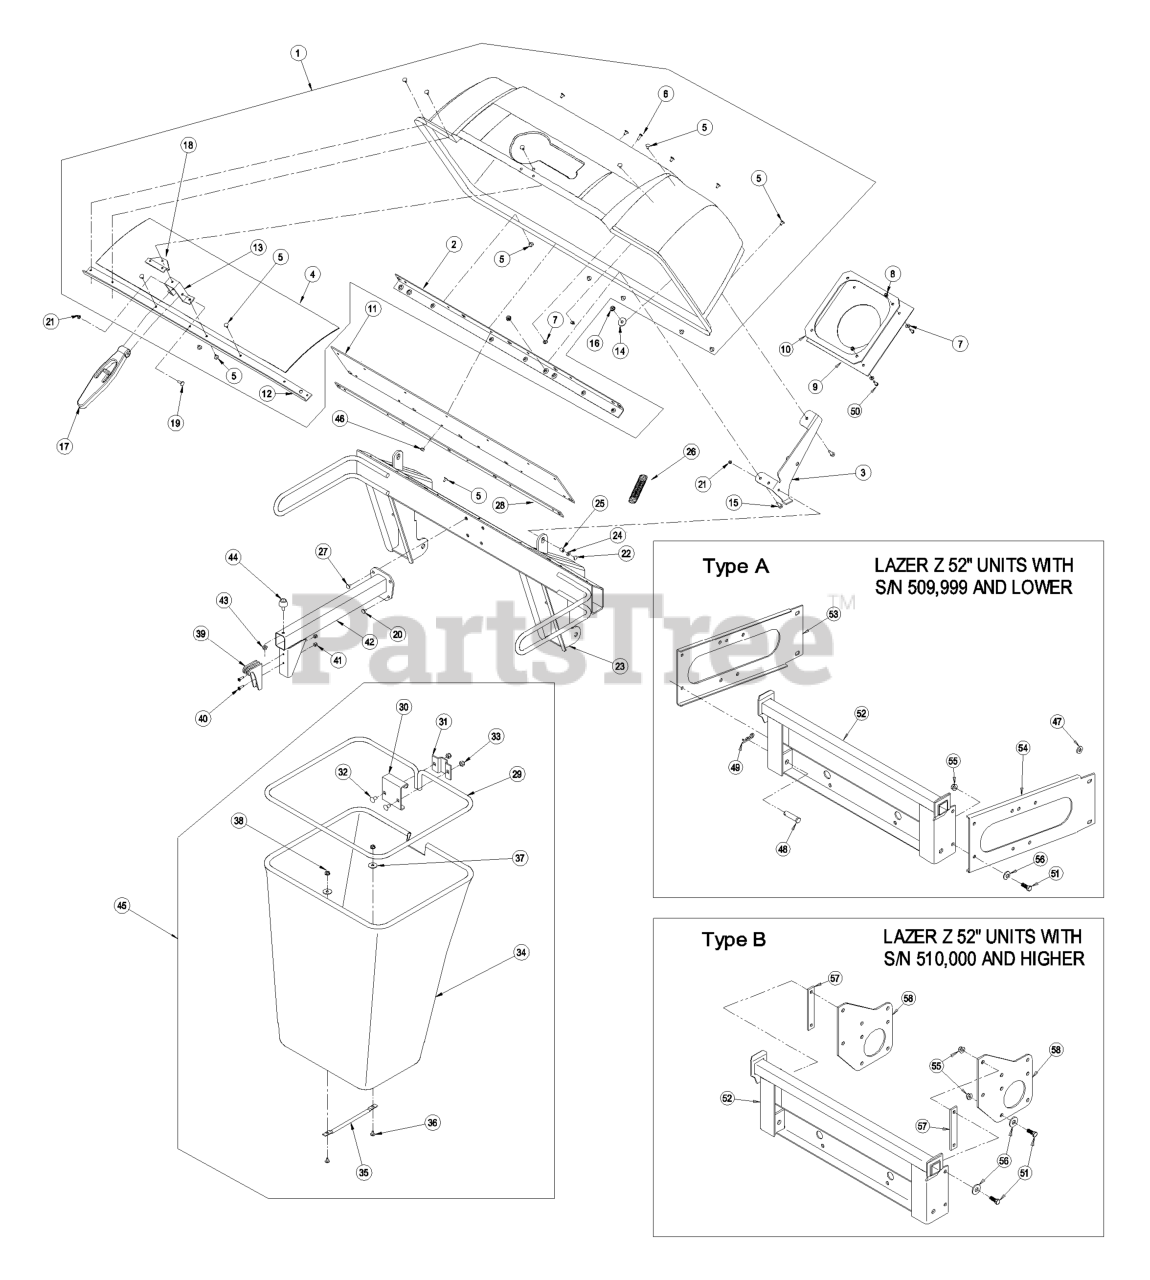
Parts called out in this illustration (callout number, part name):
1	ASM, HOOD
2	STIFFENER-BAGGER, TOP
4	SCREEN-BAGGER
5	RIVET-BLIND
6	SCREW-HEAD, TRUSS
7	WASHER-FLAT
8	NUT-LOCK, NI
9	SEAL-CHUTE
10	CLAMP-SEAL
11	SEAL-HOOD
12	SUPPORT-SCREEN
13	ANCHOR-LATCH
15	SCREW-HH
18	REINFORCEMENT-LATCH
19	SCREW-HH
20	SCREW-HSBH
21	NUT-LOCK, NI
22	SCREW-HH
23	UPRIGHT-BAGGER
24	WASHER-FLAT
26	SPRING-EXTENSION
27	SCREW-HH
28	PLATE-BACKING
29	FRAME-BAG
30	HANGER-BAG
32	BOLT-CARR
33	NUT-LOCK, NI
35	HANDLE-BAG
36	BOLT-CARR
38	NUT-LOCK, NI
40	SCREW-PPH
42	SUPPORT-BAG
46	NUT-LOCK, SIDE
47	SPACER
48	PIN-CLEVIS
49	PIN-COTTER
50	SCREW-PPH
51	SCREW-HH
52	MOUNT-BAGGER
53	BRACKET-FRAME, LH
54	BRACKET-FRAME, RH
55	NUT-HHF, WHIZ
56	WASHER-BELLEVILLE
57	SPACER
58	PLATE-MOUNT, BAGGER
